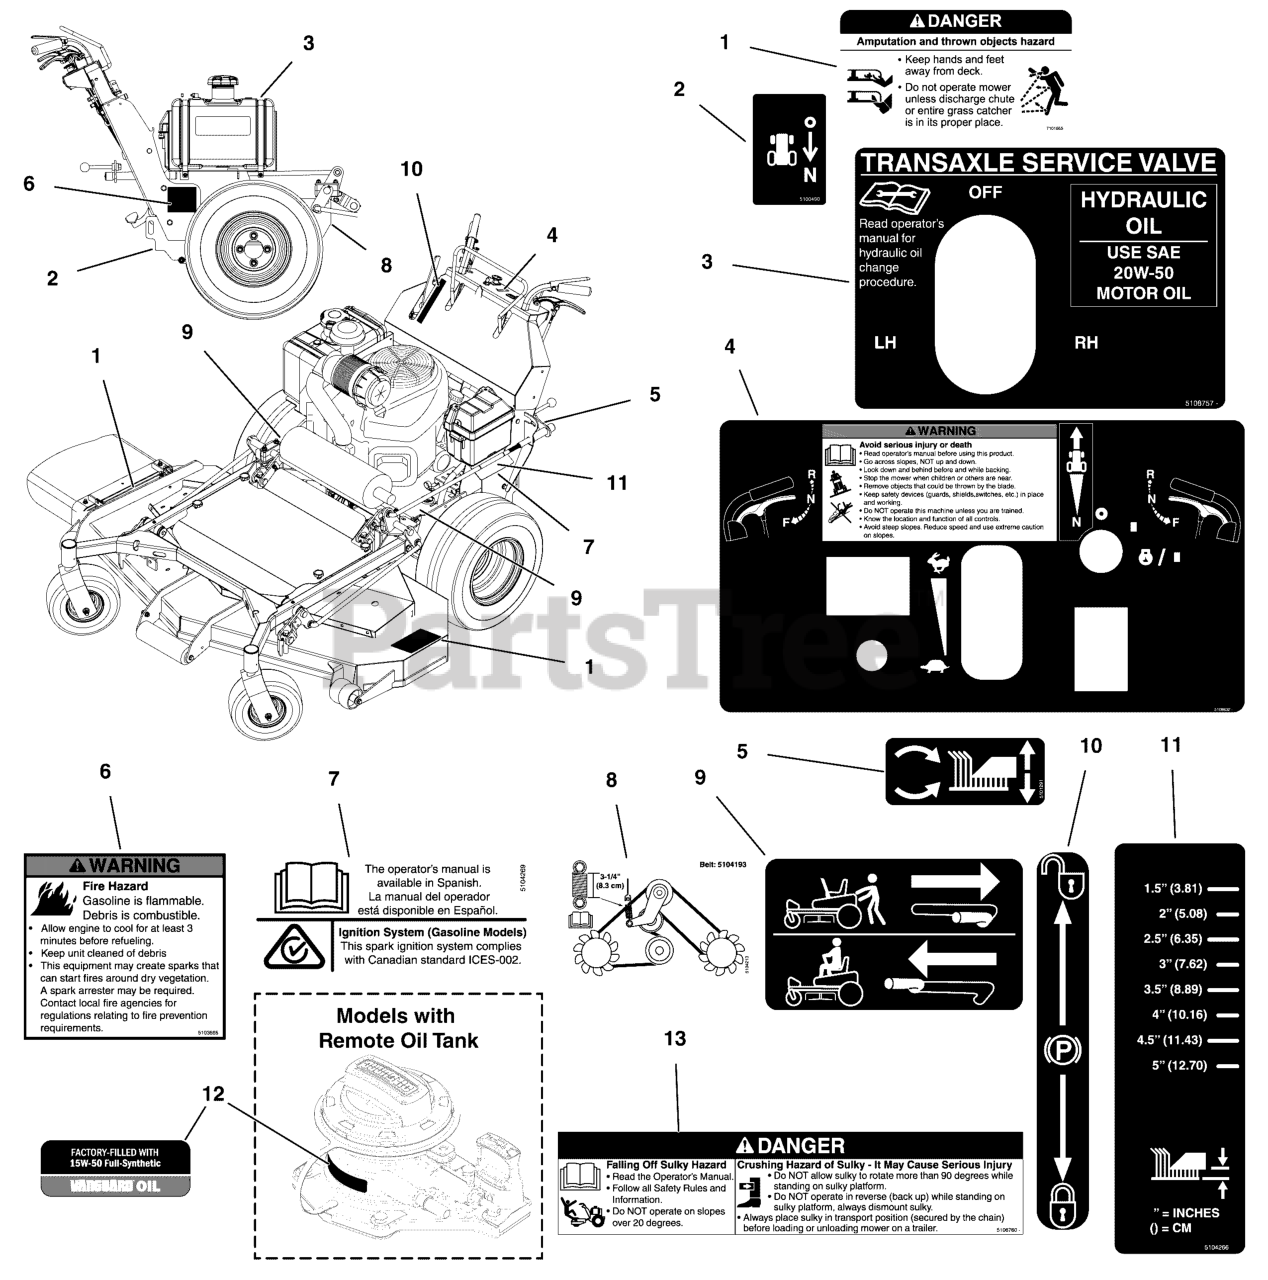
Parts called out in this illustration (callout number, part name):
1	DECAL, DANGER DO NOT OPERATE W/O DEFLECT
2	DECAL, PEDAL
3	DECAL, TRANSAXLE SELECTOR VALVE
4	DECAL, DASH PANEL, W45
5	DECAL, CUT HEIGHT, SPDD
6	DECAL, FIRE HAZARD, 3.25W X 3.0H
7	DECAL, SPANISH MANUAL, IGES, C-TICK
8	DECAL, BELT ROUTING, F/SW35
9	DECAL, TRANSAXLE RELEASE, WB
10	DECAL, PARKING BRAKE SYMBOLS
11	DECAL, CUT HEIGHT, WB, 1.5"-5"
12	LABEL, OIL INFORMATION
13	DECAL, MAIN SAFETY, SULKY
